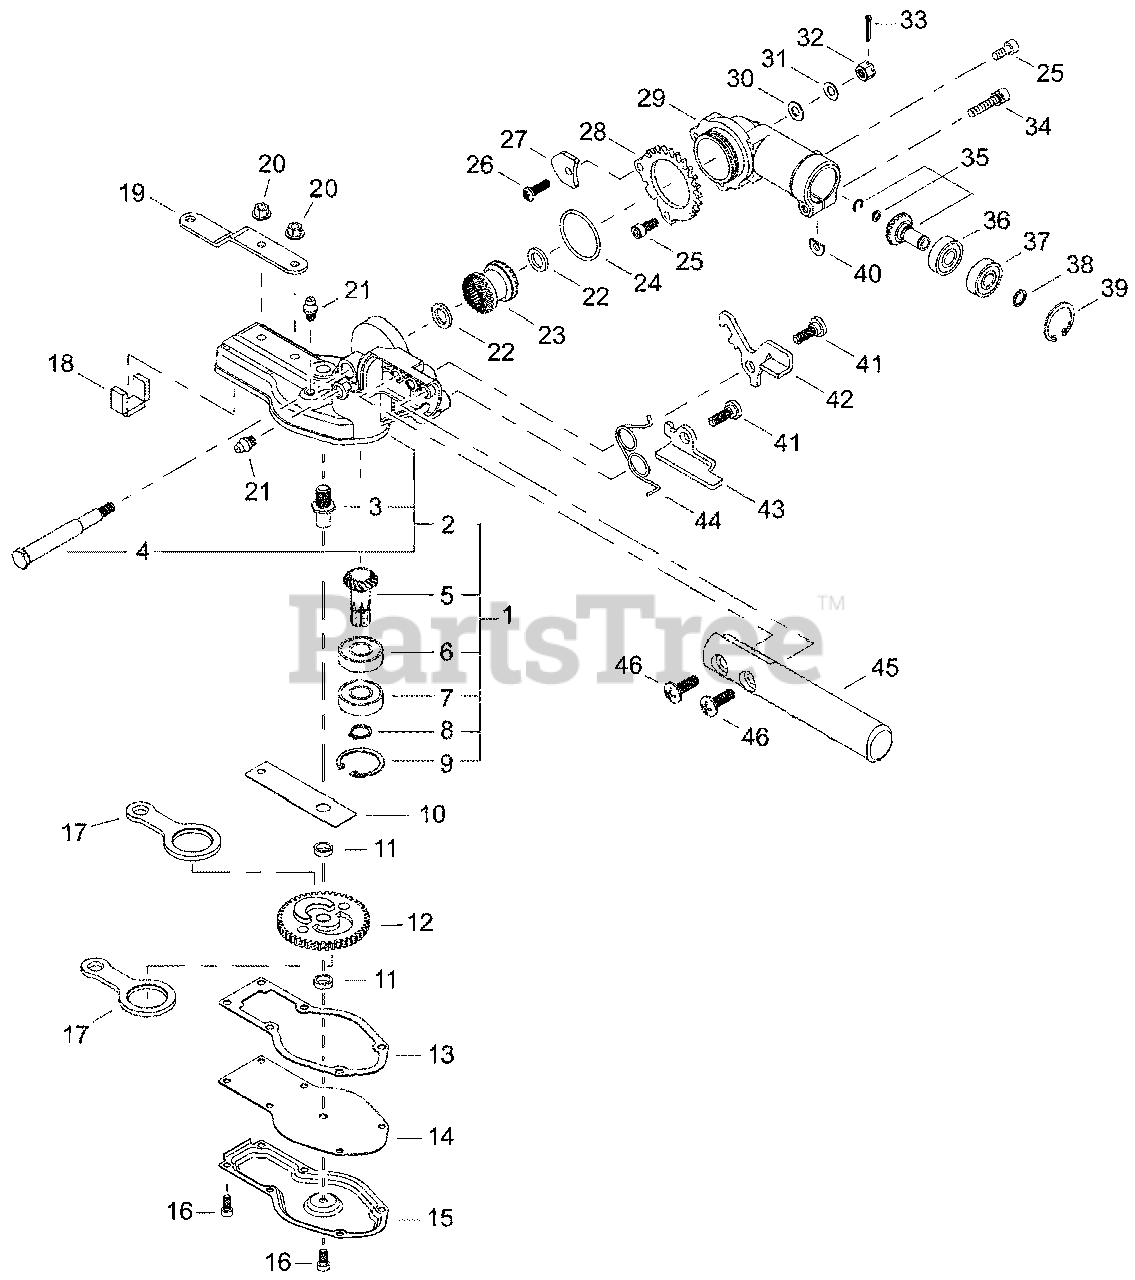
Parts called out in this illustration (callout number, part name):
1	GEAR CASE ASSY
2	CASE, GEAR - LOWER
3	PIPE, MAIN
4	SHAFT
5	GEAR - SHAFT
6	BEARING, BALL - 6001
7	BEARING, BALL - 6001ZZ
8	RING, RETAINING - 12
9	RING, RETAINING - 28
10	PLATE, GUIDE
11	SPACER
12	CAM GEAR
13	GASKET
14	PLATE, GEAR CASE
15	CASE, GEAR - LOWER
16	SCREW - 4X10
17	ROD, CONNECTING
18	SEAL, FELT
19	BRACKET, CUTTER
20	NUT - 5 -- FLANGE
21	FITTING, GREASE
22	COLLAR
23	GEAR SET - BEVEL
24	O-RING
25	SCREW - 5X12
26	SCREW - 5X16
27	STOPPER PLATE
28	PLATE, ADJUST
29	CASE, GEAR - UPPER
30	WASHER - 6
31	WASHER - CONICAL
32	NUT - CASTLE
33	PIN, SPLIT
34	SCREW - 5X25
35	GEAR - BEVEL
36	BEARING, BALL - 609
37	BEARING, BALL - 609ZZ
38	RING, RETAINING
39	RING, RETAINING - 24
40	SHIM
41	SCREW
42	LEVER, LOCK
43	LEVER, LOCK
44	SPRING
45	LEVER, ADJUSTMENT
46	SCREW - 6X20
